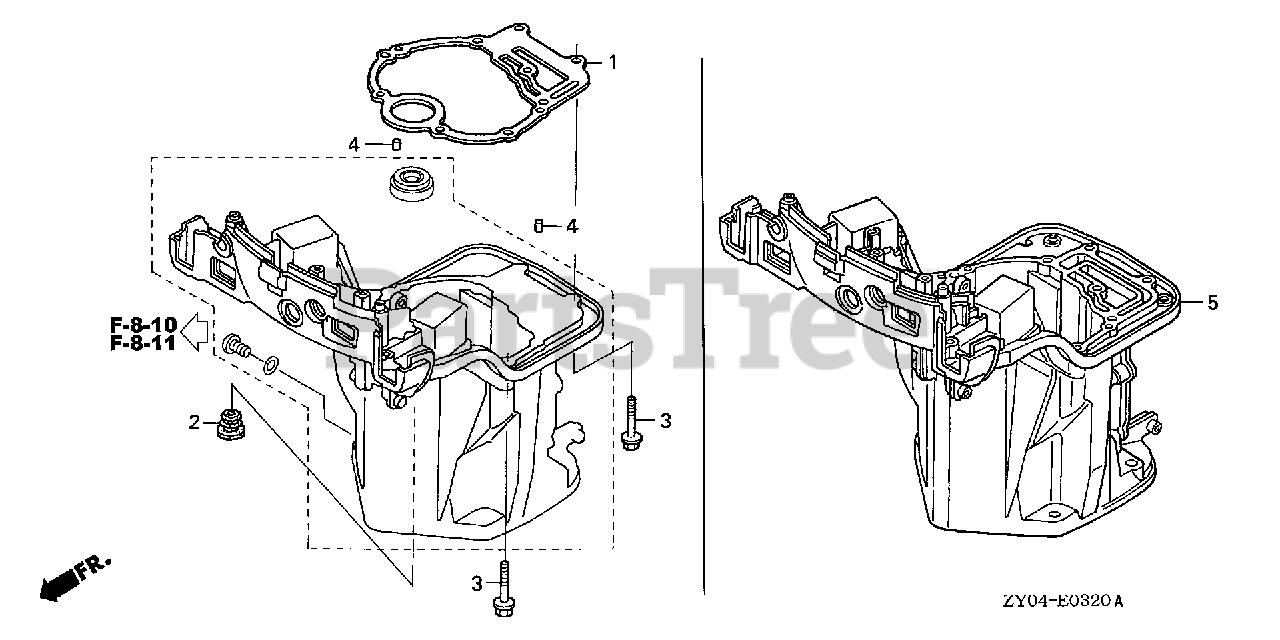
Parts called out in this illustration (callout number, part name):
1	GASKET, OIL PAN
2	GROMMET, WATER TUBE
3	BOLT, FLANGE (8X35)
4	PIN, DOWEL (6X10)
5	CASE, OIL *NH282MU* (OYSTER SILVER METALLIC-U)
